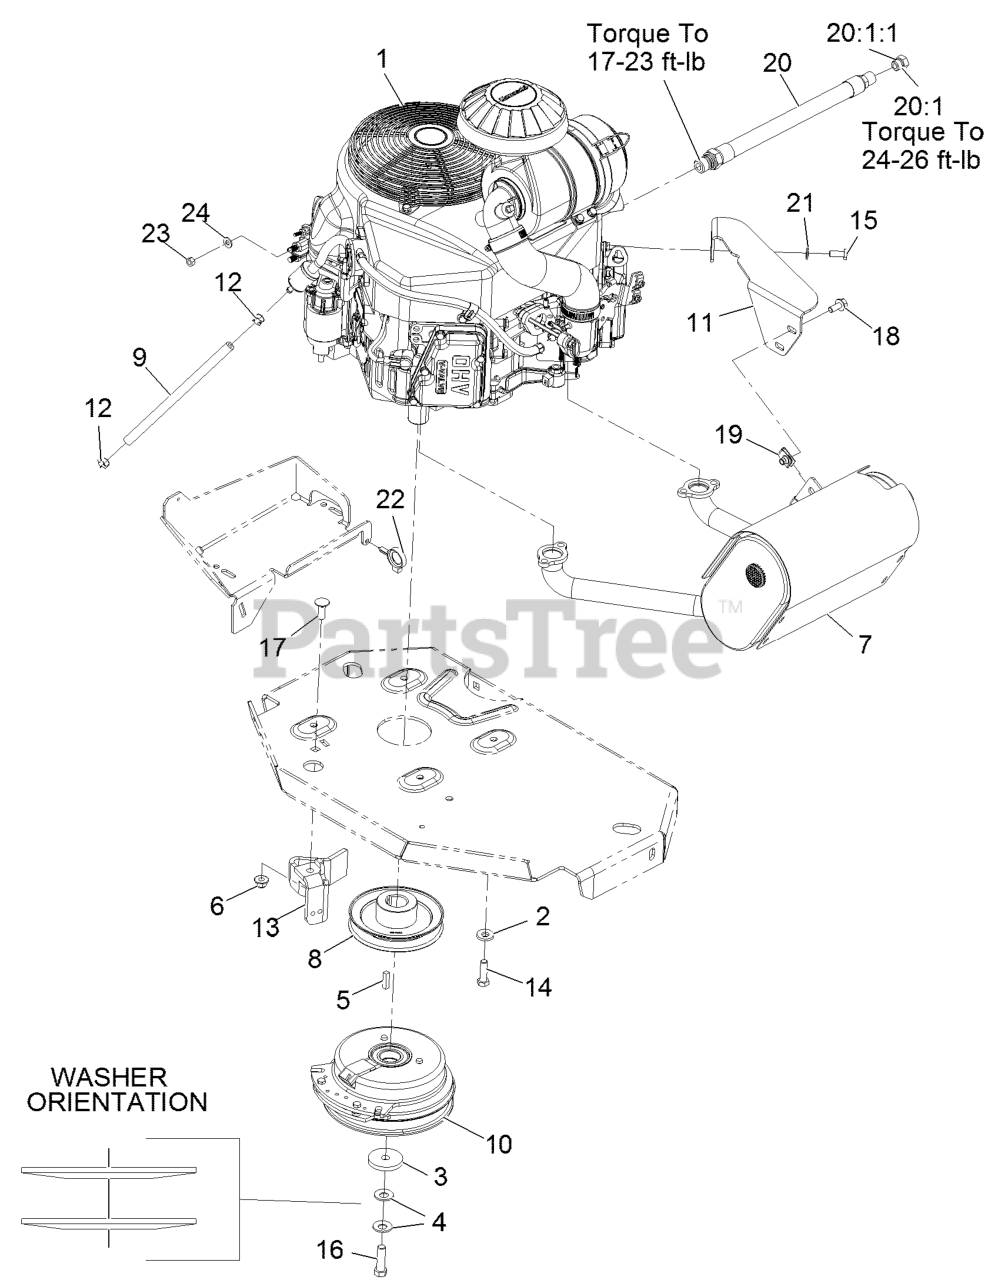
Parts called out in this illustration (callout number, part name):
1	Engine-Kawasaki
2	WASHER-BELLEVILLE
3	WASHER-CLUTCH
4	WASHER-SPRING
6	NUT-HF, NI
7	MUFFLER
8	SHEAVE-PUMP, DRIVE
9	HOSE-FUEL
11	BRACKET-MUFFLER
12	CLAMP-HOSE
13	CLUTCH-ANCHOR
14	SCREW-HH
15	SCREW-HHF
16	SCREW-HH 7/16-20 X 1 1/2 W/LOCTITE
17	SCREW-CARR
18	SCREW-HHF
20	ENGINE OIL DRAIN HOSE ASM
20:1	PLUG-HH
20:1:1	O-RING
21	WASHER-SPRING
22	CLAMP-HOSE
23	NUT-HEX
24	WASHER-FLAT
